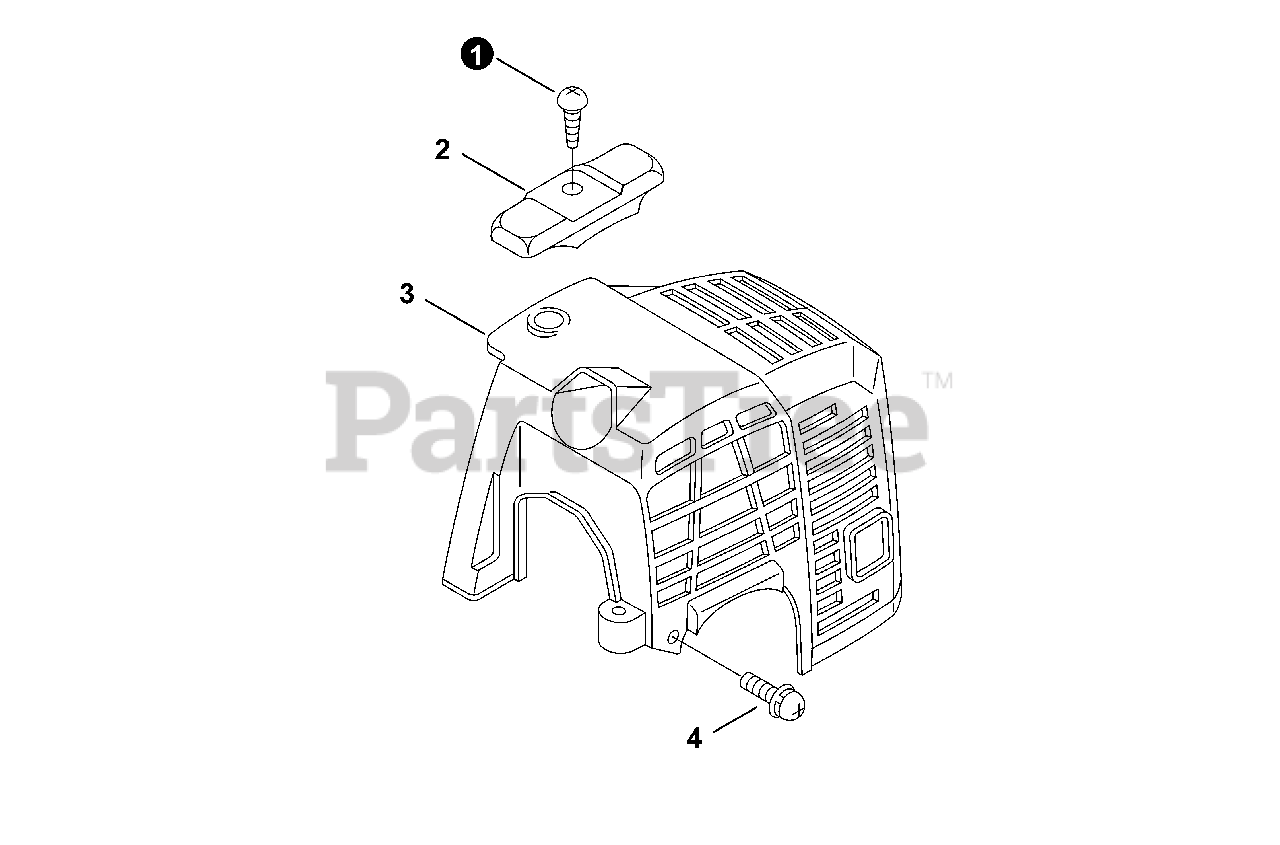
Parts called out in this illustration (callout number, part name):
1	SCREW, TAPPING 5×20
2	GUARD, TOP
3	COVER, ENGINE
4	SCREW 4×16
